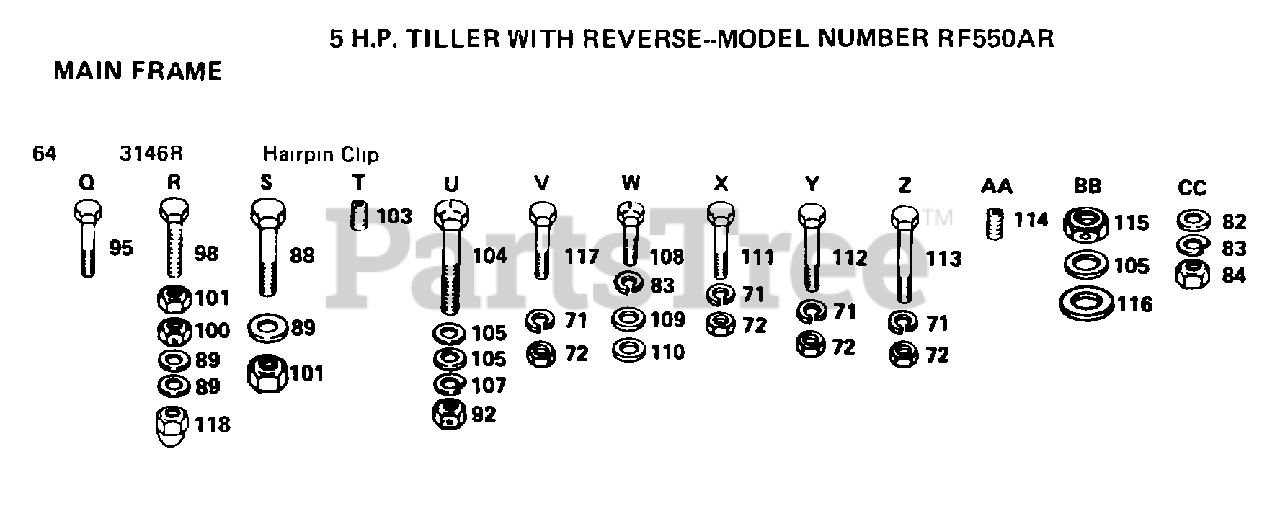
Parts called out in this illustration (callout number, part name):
64	RETAINER.SPRING
71	LOCKWASHER
72	NUT.HEX.5/16-18
82	WASHER
83	LOCKWASHER
89	WASHER
92	GRIPCO NUT
101	NUT.HEX.3/8-16UNC
103	SET SCREW
104	BOLT.3/8-24X3.75
105	WASHER
107	LOCKWASHER
108	BOLT
109	WASHER
110	WASHER
111	BOLT
117	BOLT.HEX.5/16-1.5
